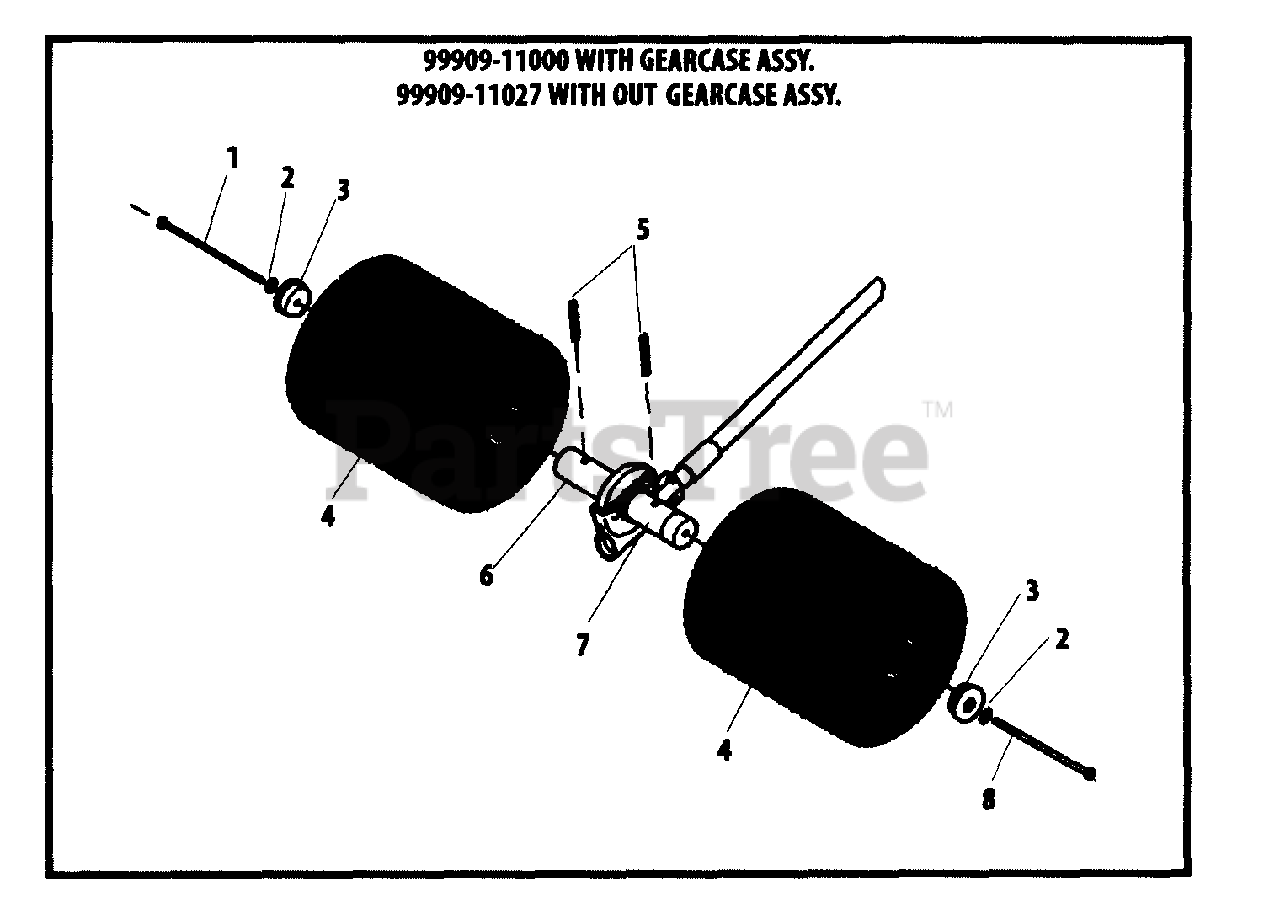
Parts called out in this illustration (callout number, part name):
1	RIGHT HAND THREAD HEX - BLACK
2	WASHER
3	CAP
4	BRISTLE BRUSH
6	RIGHT HAND THREAD CORE
7	LEFT HAND THREAD CORE
8	RIGHT HAND THREAD HEX (SILVER)
